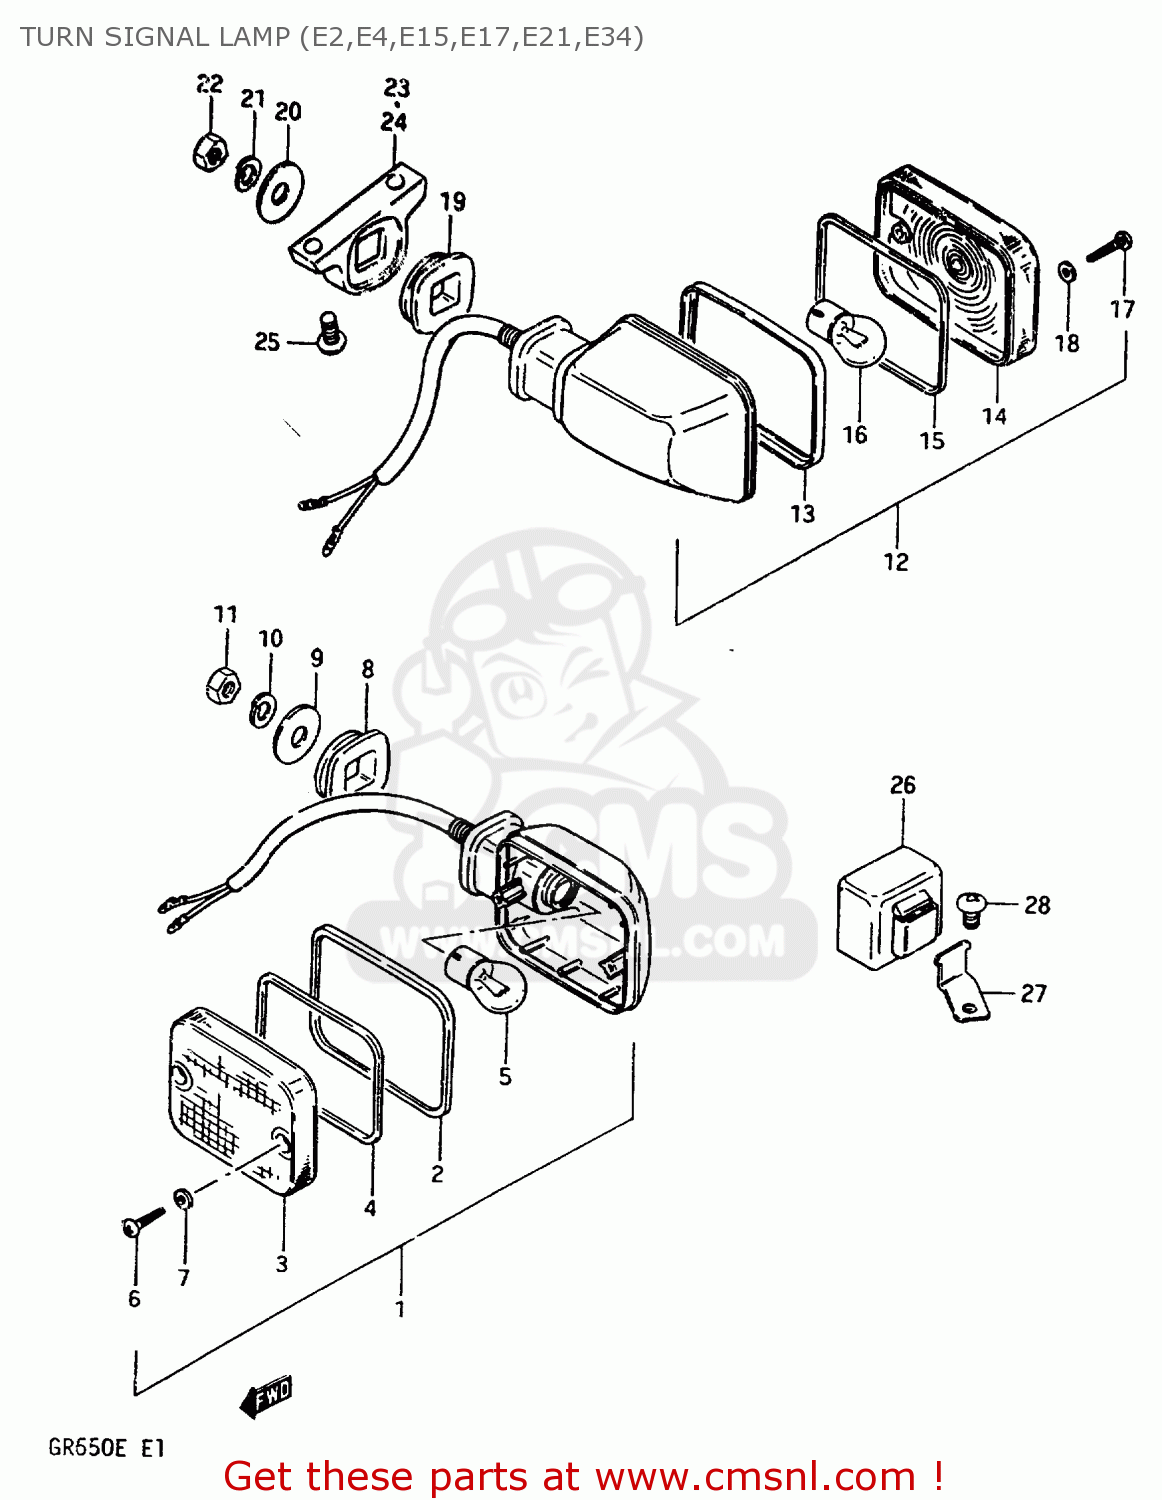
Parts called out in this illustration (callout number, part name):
1	LAMP ASSY, FRONT TURN SIGNAL
2	RIM
3	LENS
4	GASKET (NAS)
5	BULB(12V21W)
6	SCREW
7	GASKET (NAS)
8	CUSHION
9	WASHER (10.5X30X2.3)
10	LOCK WASHER
11	NUT
12	LAMP ASSY, REAR TURN SIGNAL
13	RIM
14	LENS
15	GASKET (NAS)
16	BULB(12V21W)
17	SCREW
18	GASKET (NAS)
19	CUSHION
20	WASHER (10.5X30X2.3)
21	LOCK WASHER
22	NUT
23	BRACKET,REAR TURN SIGNAL
24	BRACKET,REAR TURN SIGNAL
25	SCREW
26	RELAY,TURN SIGNAL
27	BRACKET,TURN SIGNAL RELAY
28	SCREW
